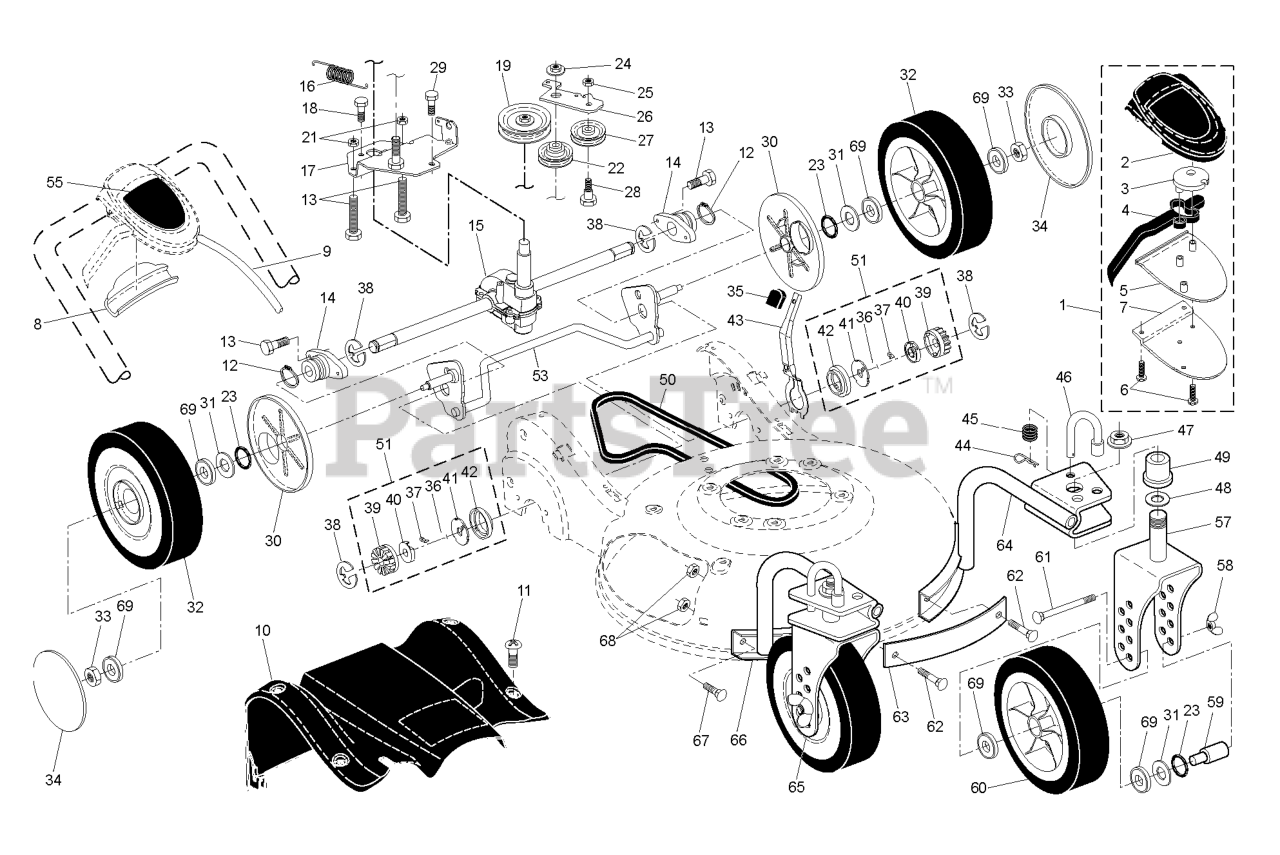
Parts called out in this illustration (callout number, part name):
1	CONTROL.DR.HV.RWGD.GRY/BLU
2	COVER TOP AUTO WALK CONTROL
3	PULLEY.CAM.DRIVE.CONTROL.HV
4	LEVER
5	COVER BOTTOM AUTO WLK CONTROL
6	SCREW, PHILLIPS HEAD 10 X 5/8
7	BRACKET, DRIVE CONTROL
8	EZ WALK SNAP COVER PLATE
9	ASM.CABLE.
10	COVER ASM. DRIVE
11	SCREW
12	RETAINING RING (2 2)(3 2)
13	RP SCREW
14	BEARING.SUPPORT.ASSEM
15	TRANSMISSION.ASM.RGD.EZ.21
16	SPRING.RETURN
17	ARM.IDLER.BZP
18	Screw, Hex Washer Head #10-24 x .668
19	RP PULLEY DRIVE
20	FLANGED LOCKNUT 3/8-16 ZINC
21	NUT
22	PULLEY.IDLER.V-BELT
23	O-RING
24	NUT
25	NUT.CENTERLOCK.5/16-
26	BRACKET
27	IDLER PULLEY
28	SHOULDER BOLT
29	SCREW 14-20 X 5/8
30	DUST COVER, WHEEL
31	WASHER.FLAT.1/2
32	WHEEL.9X2.25.PR.JUNG.BLK
33	HEX FLANGE LOCKNT
34	RB HUBCAP.3-SPOKE.SILVER
35	KNOB.SELECTOR.SPRG.H-GRY (2 2)
36	SPRING, TORSION
37	PAWL.DRIVE.21.EZ-WALK
38	E-RING 7/16 RE
39	GEAR, PINION
40	RETAINER.DRIVE.21.EZ-WALK.LT
41	DISC.DRIVE.21.EZ-WALK
42	SEAL.PINION
43	LEVER, SELECTOR, HEIGHT, REAR
44	COTTER PIN (3 2)(2 2MC)
48	WASHER.FLAT.1/2
50	BELT.DRIVE.EZ.WALK.HI-VAC
51	PINION ASSY, LH
52	RETAINER, DRIVE, RH
53	AXLE.ASM.REAR.TORQUE.BZP
54	PINION ASSY, RH
55	DECAL, DRIVE
57	BRACKET, CASTER
58	NUT.WING.5/16-18.YELLOW
60	WHEEL.9X2.25.LP.JUNG.SILV.BB.1
61	CARRIAGE BOLT
63	STRAP, FRONT
64	SUPPORT TUBE ASSY, LH BLK
65	BRACKET CASTER WHEEL, RH
66	SUPPORT TUBE ASSY, RH
68	NUT
69	BEARING.8".WHEEL
